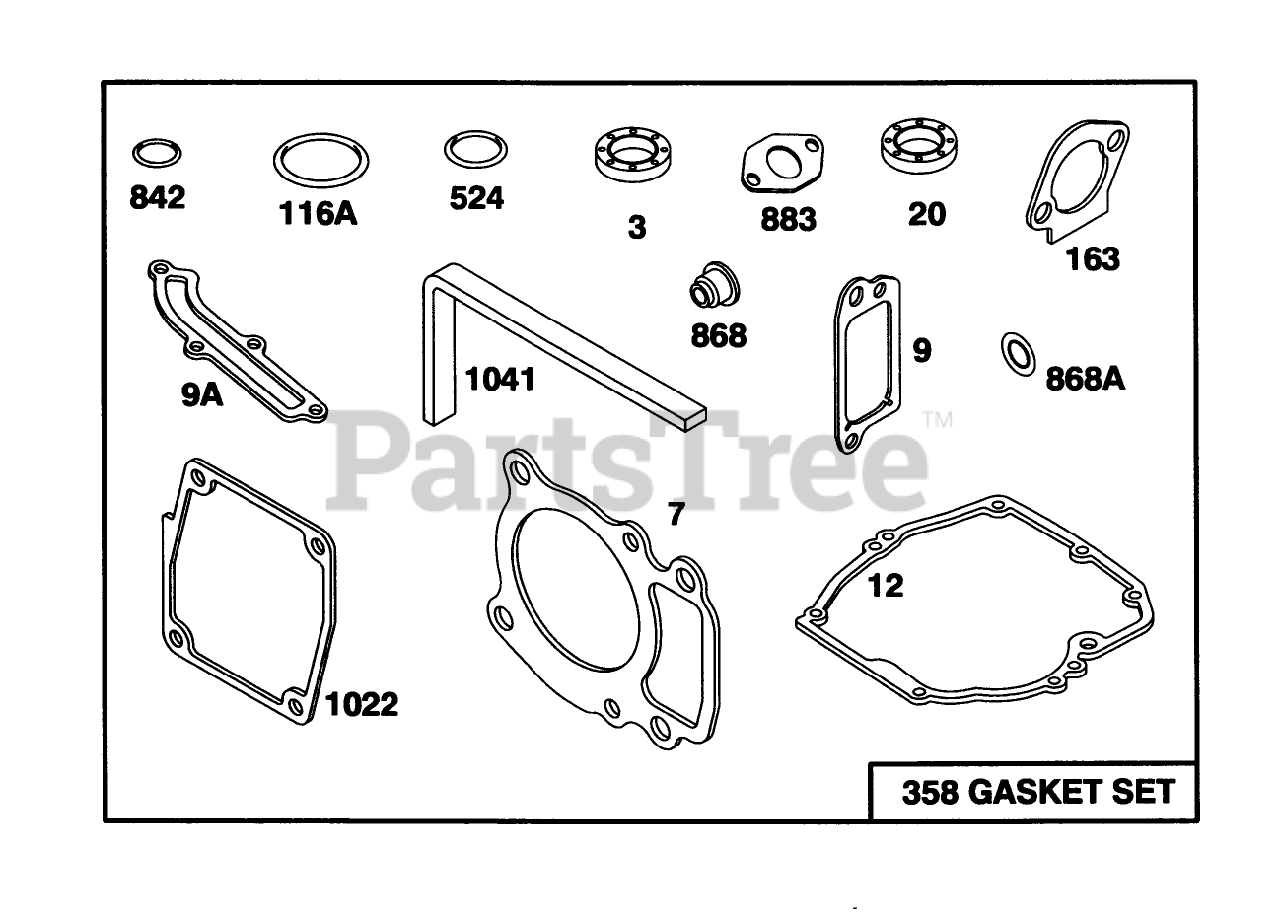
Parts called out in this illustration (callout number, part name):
7	CYLINDER HEAD GASKET
12	ENGINE BASE GASKET
20	SEAL-OIL
116A	O RING SEAL
163	AIR CLEANER GASKET
358	GASKET SET
524	O-RING
842	O-RING
1022	ROCKER COVER GASKET
